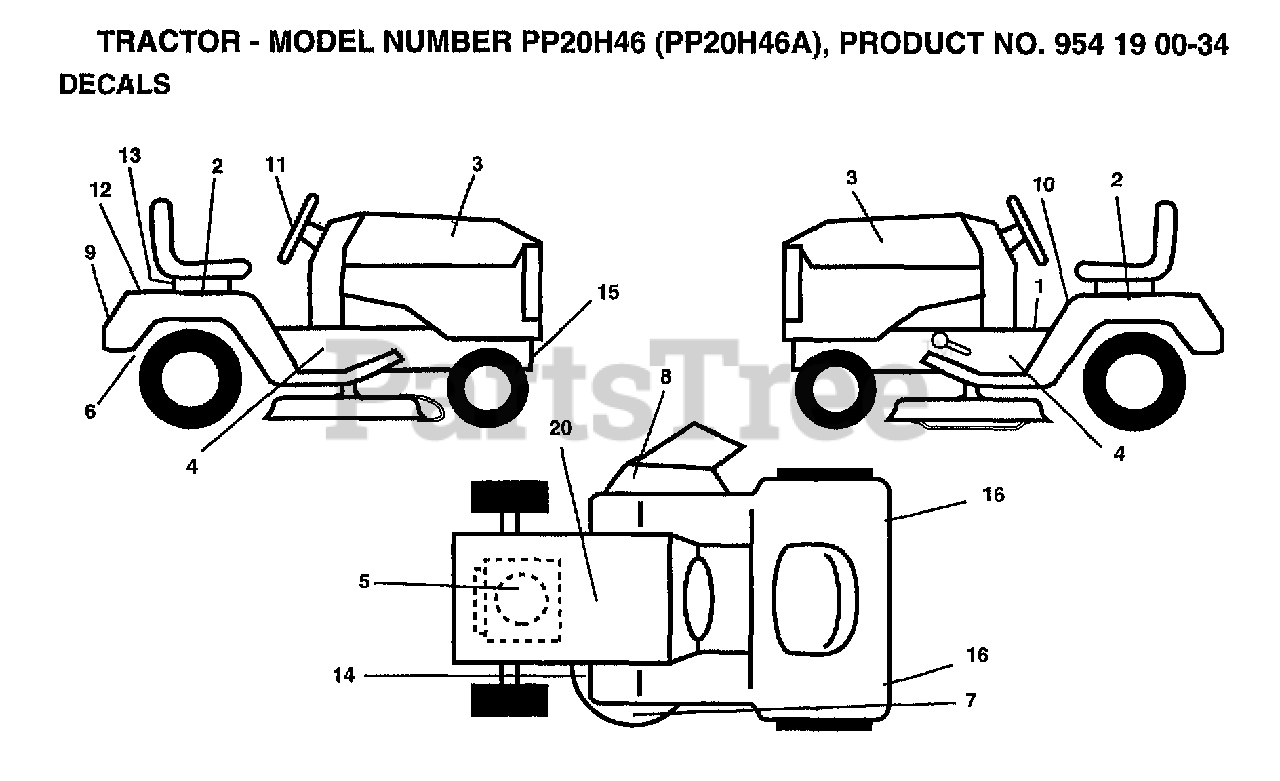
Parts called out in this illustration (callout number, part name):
1	"DECAL FENDER,OPER"
2	DECAL FENDER AUTO
3	DECAL HOOD PREDAT
4	"DECAL.CHASSIS.46"".20HD"
5	DECAL .B&S.20HP
6	DECAL DRAWBAR LH
7	"DECAL,ENVIRO DECK"
8	"DECAL, WARNING"
9	DECAL FENDER DOME
10	DECAL.CAUT.ENG/FR
11	DECAL INS STRG WH
12	DECAL FENDER PRED
13	RETAINER-SPRING
15	DECAL CHASSIS PRE
16	REFLECTOR-TAIL YT
20	DECAL.BATRY.3-3908
